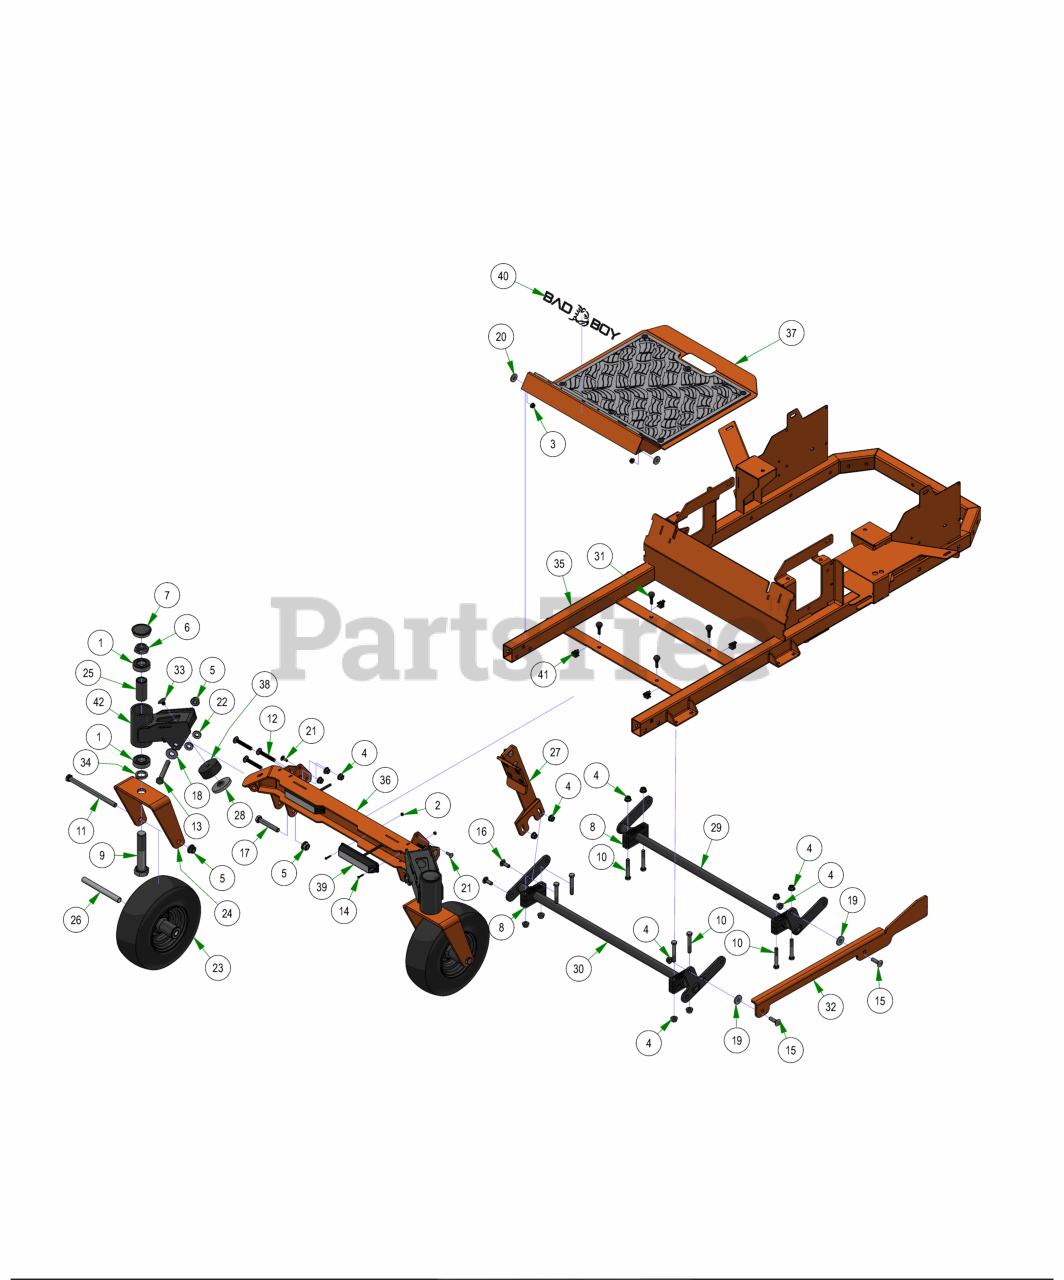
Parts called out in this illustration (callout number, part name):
1	1641 BEARING W/2 CONTACT RUBBER SEALS
2	6-32 Stainless Nylock Nut
3	1/4-20 NYL INSERT FLANGE LOCKNUT ZINC
4	3/8-16 NYLON INSERT FLANGE LOCKNUT (GR.F) ZINC
5	1/2-13 NYLON INSERT FLANGE LOCKNUT ZINC
6	1"-14 NYLON INSERT JAM LOCKNUT ZINC
7	2017 Bearing Cover
8	Pillow Block Kit
9	1"-14 X 5 HEX CAP SCREW (GR.8) ZINC YELLOW
10	3/8-16 X 2-1/2 HEX CAP SCREW (GR.5) ZINC
11	1/2-13 X 7-1/2 HEX CAP SCREW (GR.5) ZINC
12	3/8" x 2 1/2" Carriage Bolt
13	1/2-13 X 3-3/4 HEX CAP SCREW (GR.5) ZINC
14	6-32 x 3/4" Stainless Pan Head Phillips Screw
15	3/8-16 X 1-1/4 CARRIAGE BOLT ZINC
16	3/8-16 X 1 CARRIAGE BOLT (GR.5) ZINC
17	1/2-13 X 3 HEX CAP SCREW (GR.5) ZINC
18	1/2 F/W USS (1-3/8" OD) ZINCC
19	.390 ID X 1.12 OD X .125 THK FLAT WASHER NYLON
20	.360 ID X .983 OD X .120 THICK FLAT WASHER NYLON
21	1/4-20 X 3/4 CARRIAGE BOLT (GR.5) ZINC
22	.505 ID X 1.000 OD X .125 THICK FLAT WASHER NYLON
23	11 x 4.00 - 5 Front Tire Assembly (Black)
24	MZ Front Fork (42" ONLY)
25	2016 Front Bearing Spacer
26	Front Wheel Spanner
27	Foot Pedal Assembly
28	E Mower Suspension Front End Compression Plate
29	Residential E Mower Rear Actuator Bar
30	Residential E Mower Front Actuator Bar
31	2023 Floor Board Rubber Bumper
32	Residential E Mower Actuator Bar Linkage
33	Ribbed Shank Push-In Rivet
34	1.02 ID X 1.38 OD X .250 THK SPACER ZINC
35	Residential E Mower Frame
36	Residential E Mower Front End
37	2024 EV Floorboard Assembly
38	E Mower Front Suspension Rubber
39	E Mower Headlight
40	Flying Bulldog Front Bumper Decal
41	Edge Clip With Ziptie
42	Residential E Mower Suspension Arm
